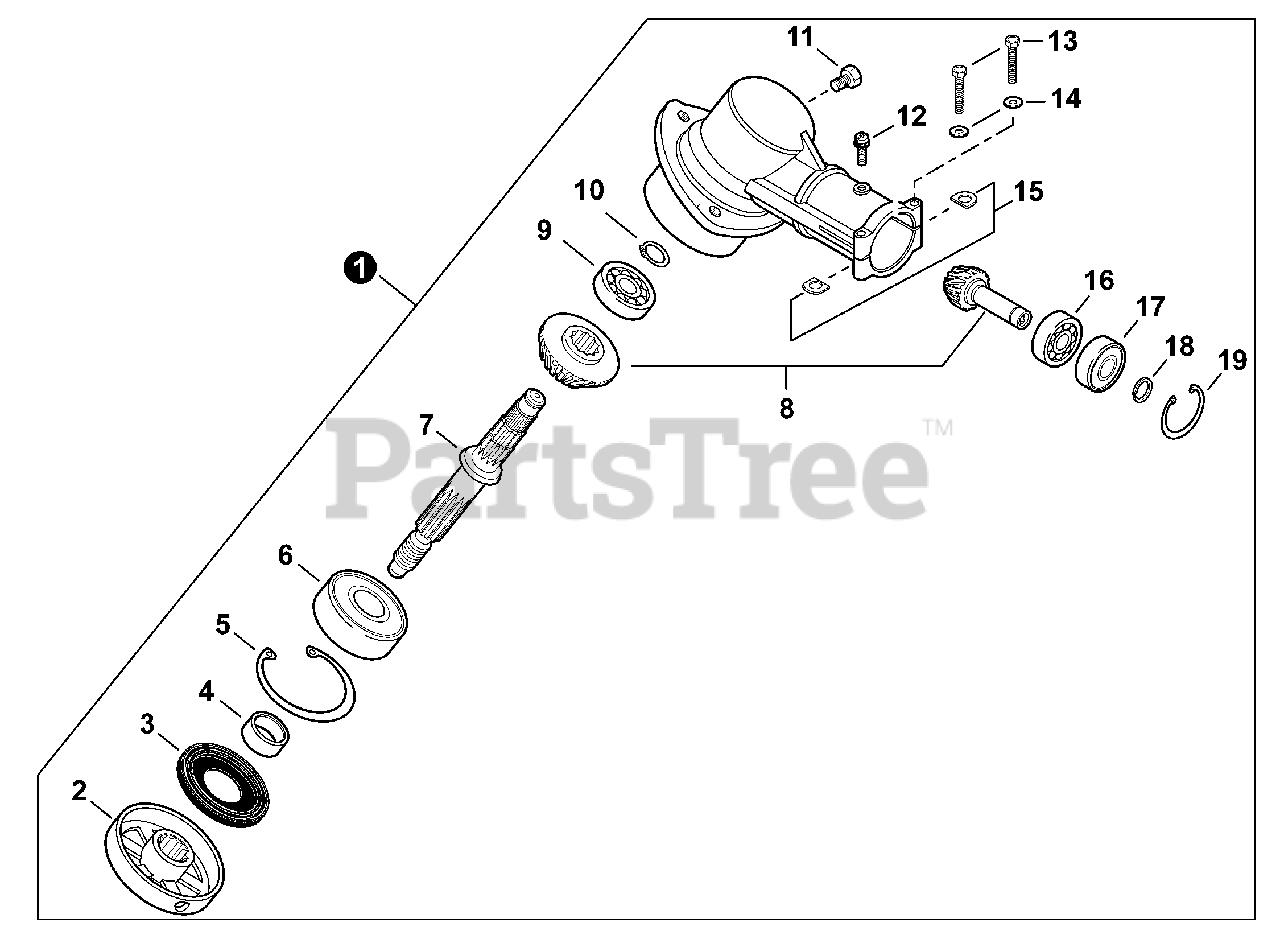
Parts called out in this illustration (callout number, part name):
1	GEAR CASE ASSY
2	PLATE, ADAPTOR - UPPER
3	SEAL, OIL 22
4	SPACER 11.8×15×9
5	RING, SNAP 32
6	BEARING, BALL 6201
7	SHAFT, GEAR
8	GEAR SET
9	BEARING, BALL 609
10	RING, SNAP 12
11	BOLT M8×8
12	SCREW 5×10
13	BOLT 5×35 SP
14	WASHER, FLAT 5.5×10×0.8
15	D-WASHER
16	BEARING, BALL 6900
17	BEARING, BALL 6900-Z
18	RING, SNAP 10
19	RING, SNAP 22
